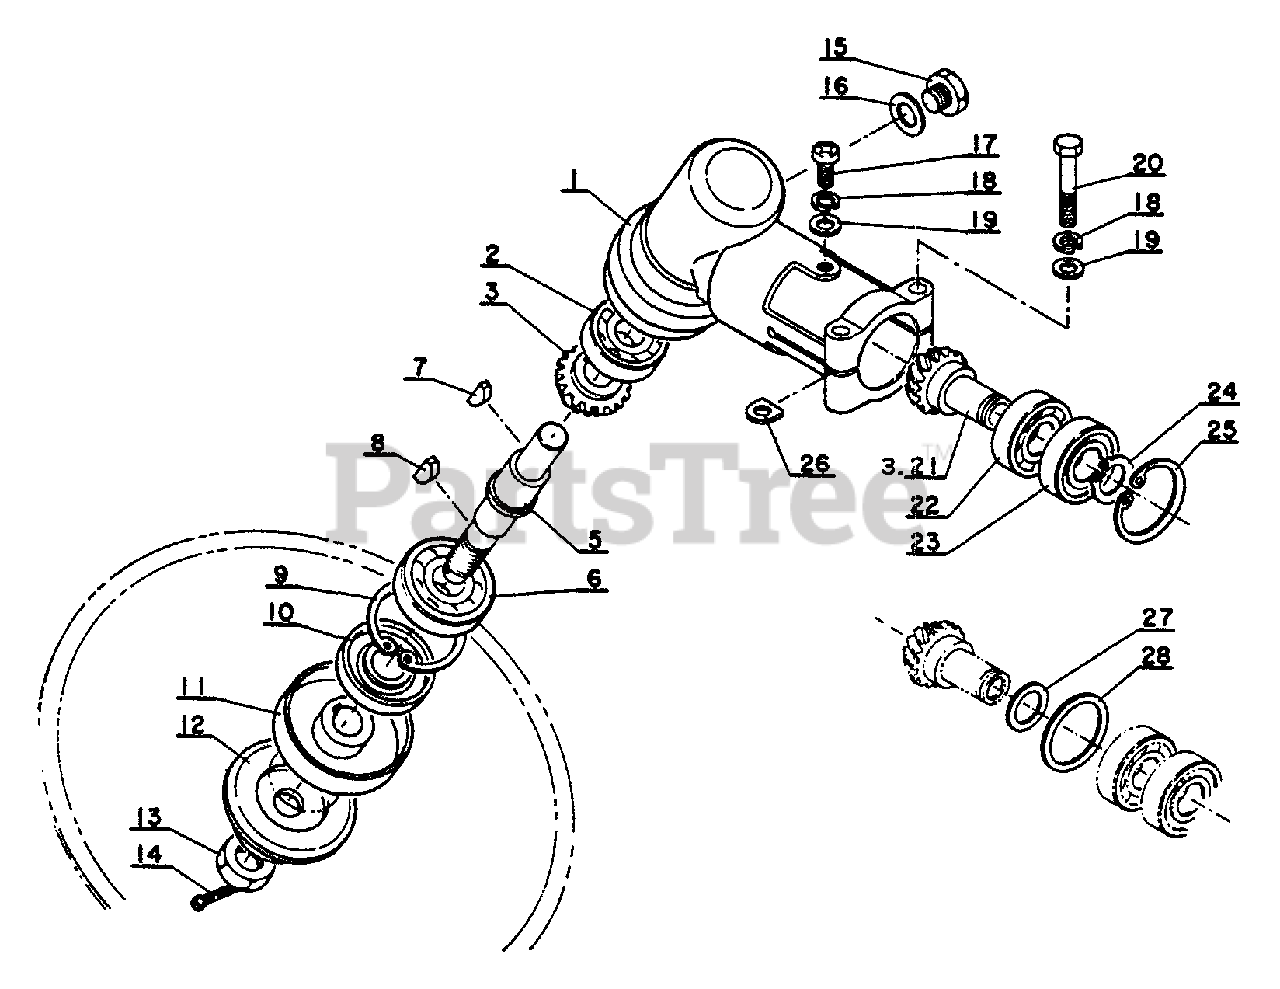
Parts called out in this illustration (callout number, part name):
1	CASE, GEAR
2	BEARING, BALL 6000
3	GEAR SET
4	WASHER
5	DRIVESHAFT
6	BEARING, BALL - 6201 C3
9	RING, SNAP Ø32
10	SEAL, OIL
11	PLATE, ADAPTER - UPPER
12	PLATE, ADAPTER - LOWER
14	PIN, COTTER 2×22
15	BOLT - 8×6
16	GASKET
17	SCREW 5×10
18	WASHER, SPRING 5
19	WASHER, FLAT 5.5×10×0.8
20	BOLT 5×30
21	GEAR SET
22	BEARING, BALL 6001
23	BEARING, BALL 6001
24	RING, RETAINING - 12
25	RING, SNAP 28
